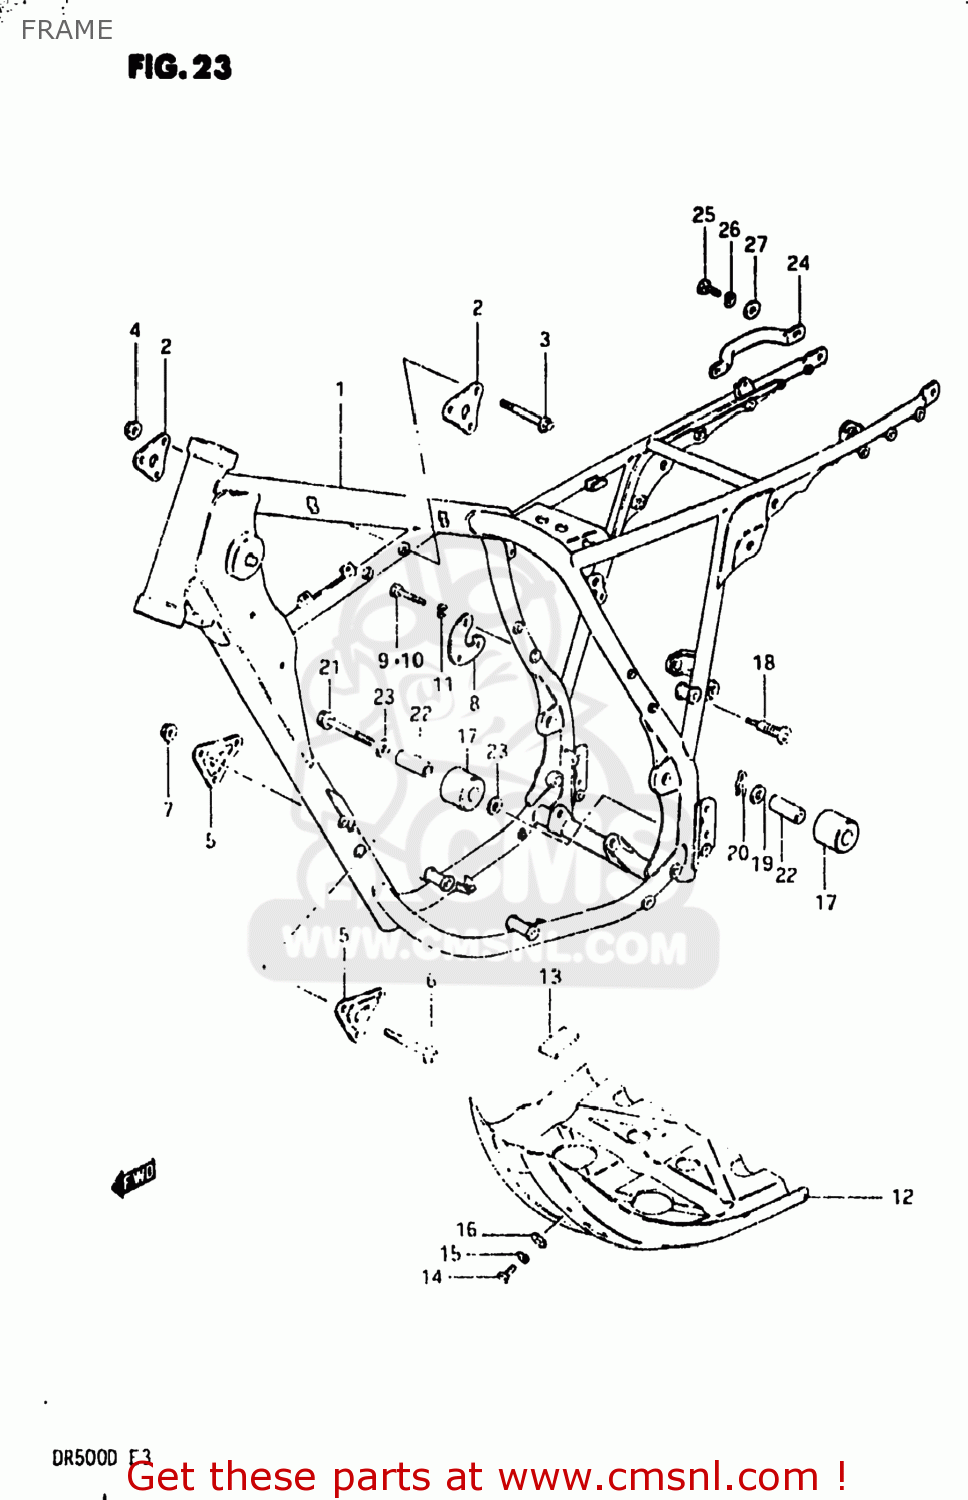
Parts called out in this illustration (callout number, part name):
1	FRAME
2	PLATE,ENGINE MOUNTING,UPPER
3	BOLT
4	NUT
5	PLATE,ENGINE MOUNTING,FRONT
6	BOLT 8X67
7	NUT
8	PLATE,ENGINE MOUNTING
9	BOLT
10	BOLT 8X50
11	LOCK WASHER
12	PLATE,ENGINE,UNDER
13	CUSHION,ENGINE,UNDER
14	BOLT
15	LOCK WASHER
16	WASHER
17	ROLLER,CHAIN LENGTH CONTROL
18	BOLT,CHAIN LENGTH ROLLER
19	WASHER
20	E RING 8MM
21	BOLT(8X45)
22	SPACER,CHAIN LENGTH ROLLER
23	WASHER
24	GRIP,FRAME HANDLE
25	BOLT
26	LOCK WASHER
27	WASHER
